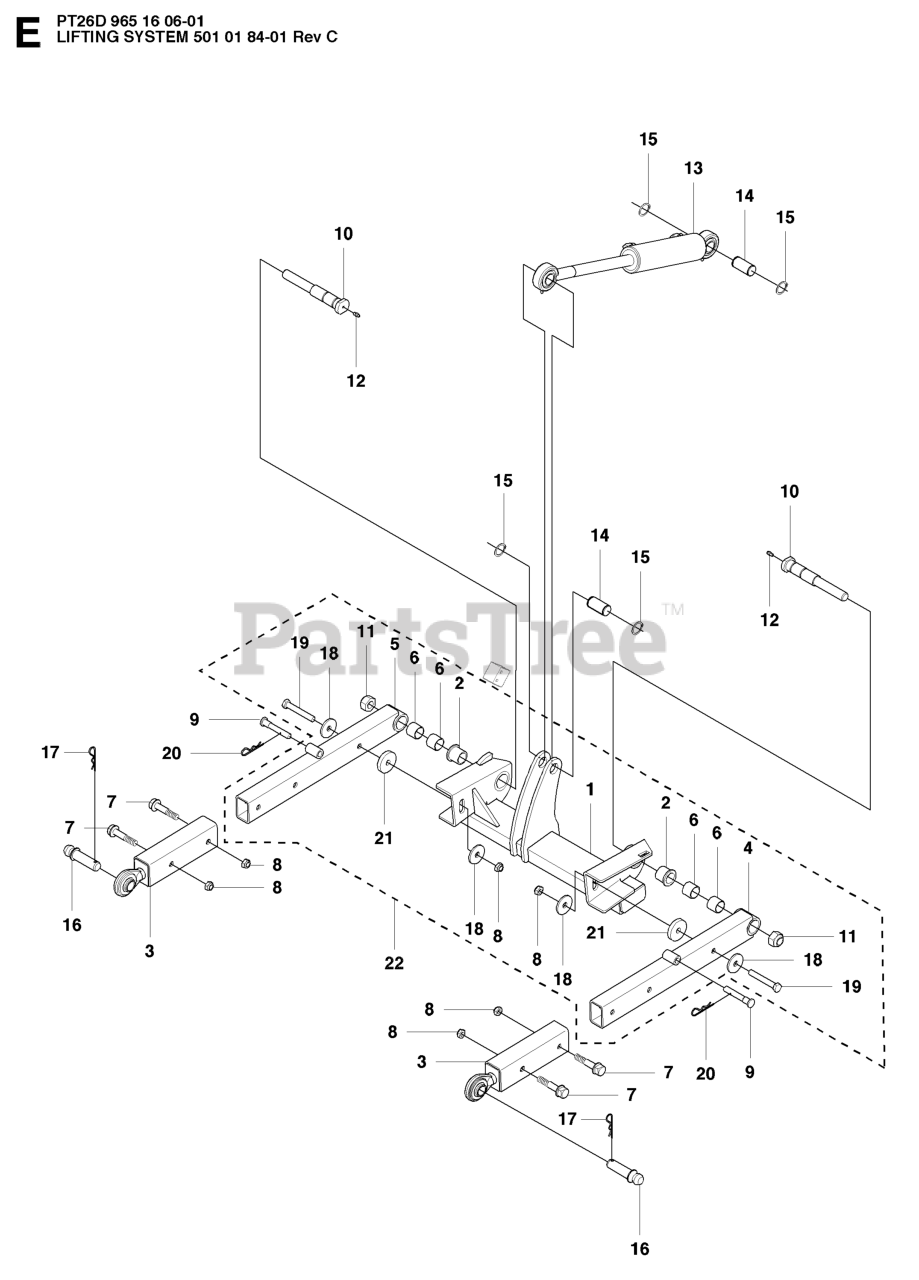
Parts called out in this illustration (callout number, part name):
1	BEAM PACKING BEAM
3	EQUIPMENT FRAME
4	LIFTING ARM LEFT
5	LIFTING ARM RIGHT
6	BEARING BUSHING
11	NUT LOCKING
12	GREASE NIPPLE
13	HYDRAULIC CYLINDER
15	RETAINING RING SGA 25
16	BOLT LIFTING ARM
